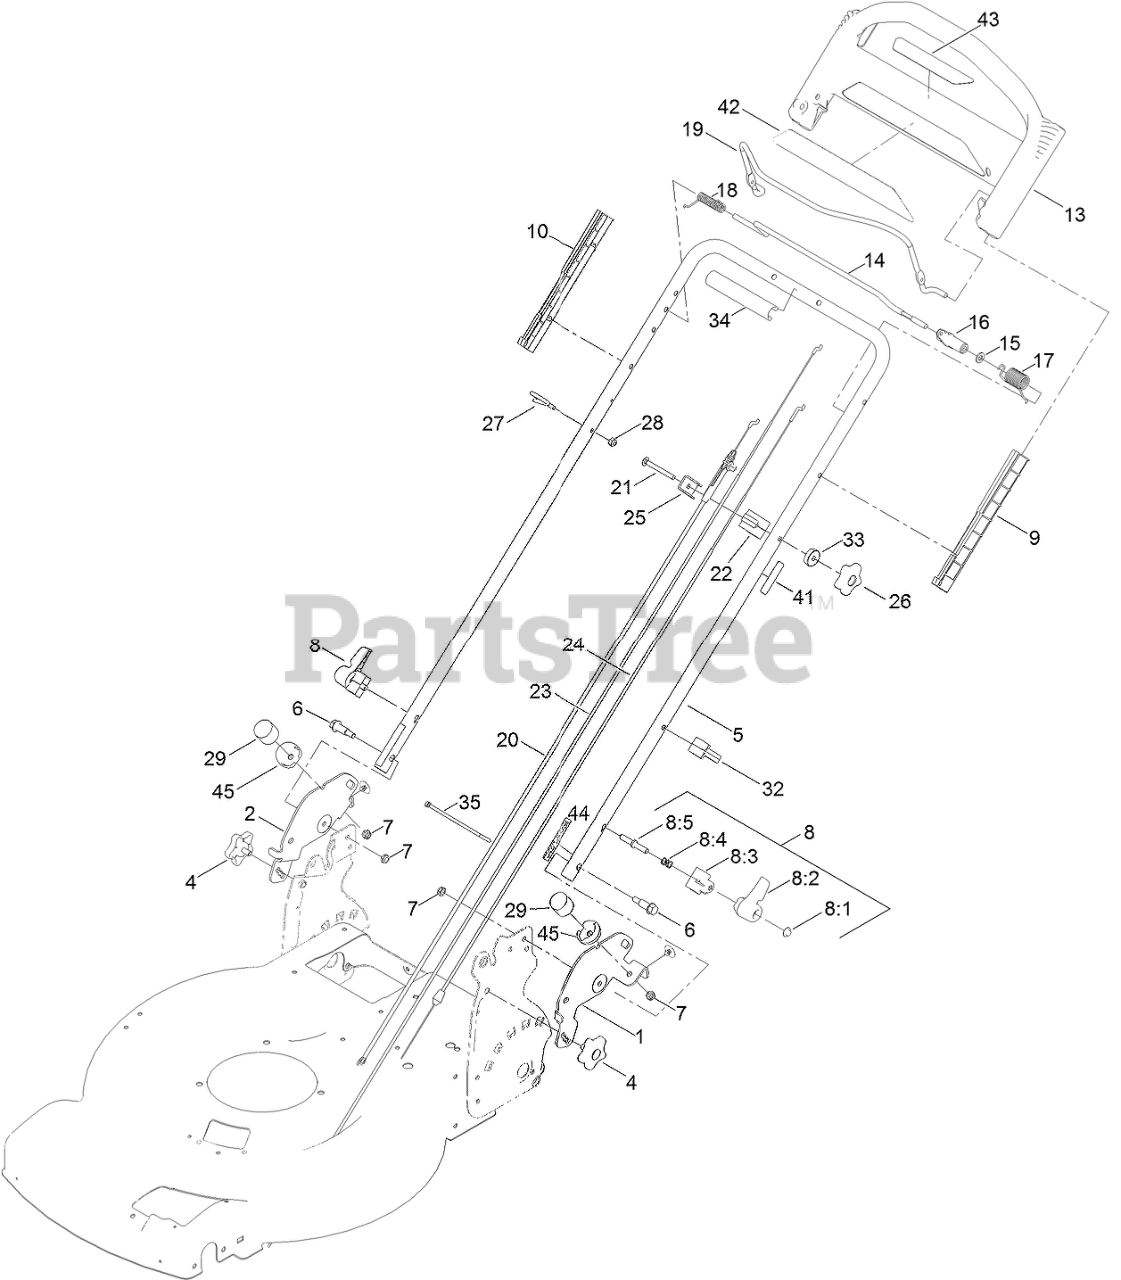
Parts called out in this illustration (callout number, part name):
1	BRACKET-FLOAT, LH
2	BRACKET-FLOAT, RH
4	KNOB-HANDLE
5	HANDLE-UPPER
6	BOLT-SHOULDER
7	NUT-LOCK, NI
8	QUICK RELEASE ASM
8:1	NUT-PUSH
8:2	LEVER
8:3	ANCHOR-SPRING
8:4	SPRING-COMPRESSION
8:5	ROD-RELEASE
9	GUIDE-LH
10	GUIDE-RH
13	HANDLE-PACE, PERSONAL
14	BAR-CONTROL, TRACTION
15	WASHER-PLAIN
16	LEVER-TRACTION
17	SPRING-TORSION
18	Spring-Torsion
19	BAIL-BRAKE
20	CABLE-BRAKE
21	SCREW-CARR
22	MOUNT-CABLE, TRACTION
23	CABLE-TRACTION, FRONT
24	CABLE-TRACTION, REAR
25	CLAMP-CABLE
26	KNOB-HANDLE, LOCKING
27	GUIDE-ROPE
28	NUT-LOCK, NI
29	BUMPER-RUBBER
32	GUIDE-CABLE
33	WASHER-CURVED
34	HANDLE-COVER
35	TIE-CABLE
41	DECAL-ADJUSTMENT
42	DECAL-POWEREVERSE
43	DECAL-INSTRUCTION, DRIVE
44	DECAL-ISOFLEX
45	COVER-BUMPER
